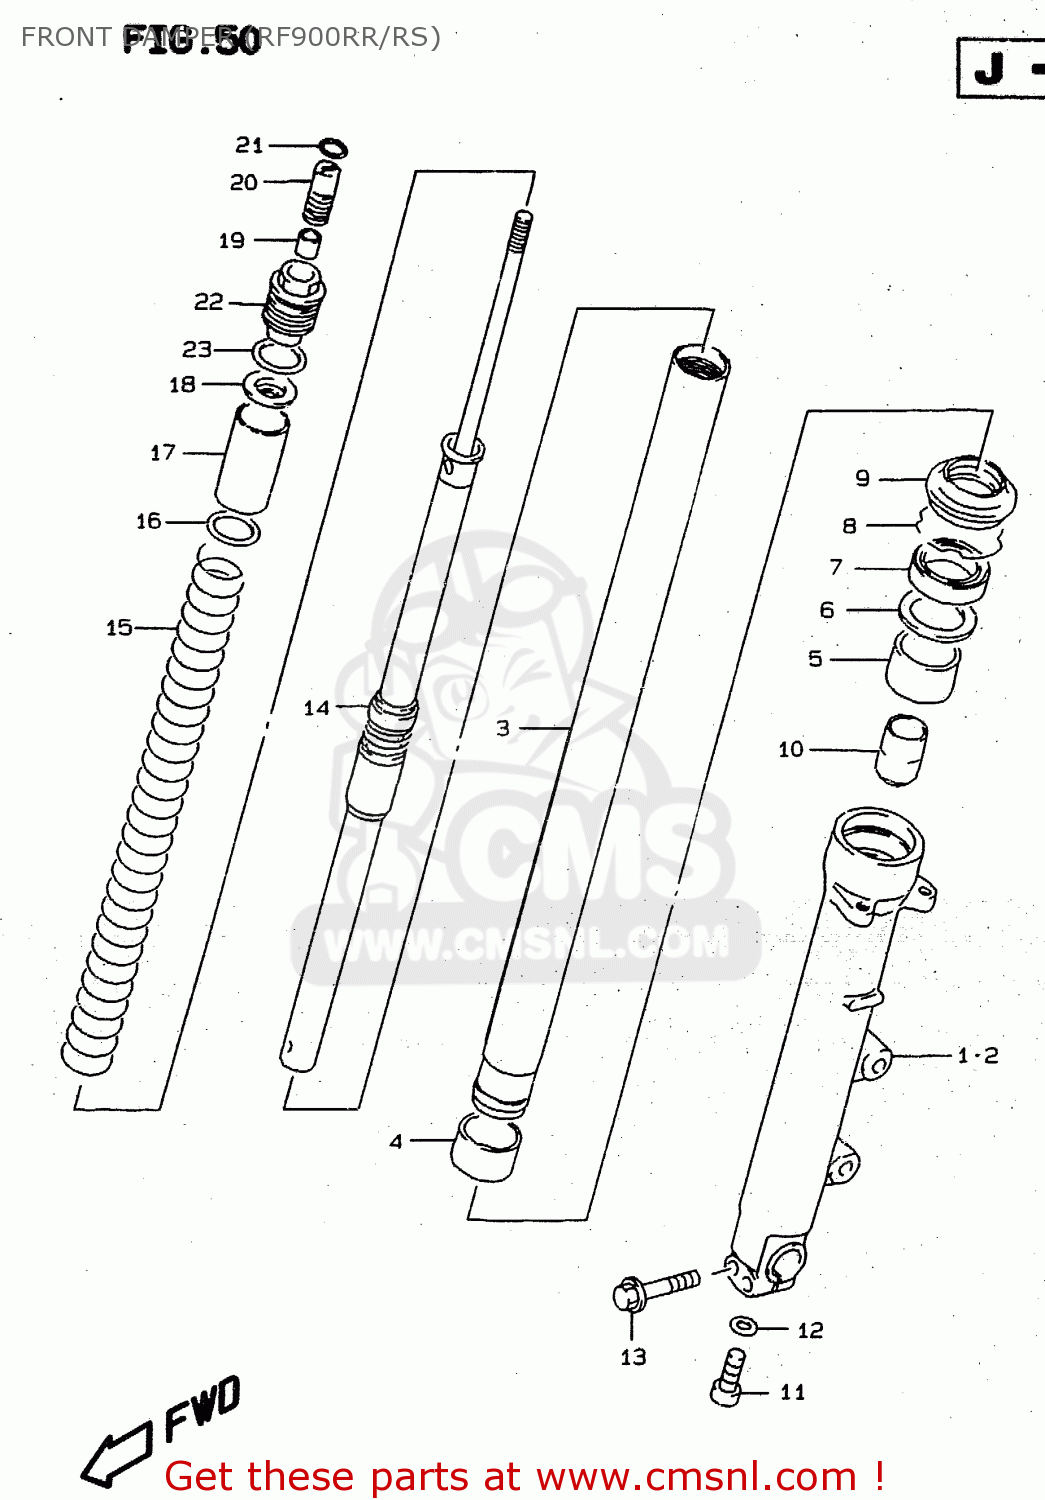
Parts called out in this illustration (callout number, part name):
1	TUBE,OUTER,R
2	TUBE,OUTER,L
3	TUBE,INNER
4	BUSH,SLIDE
5	BUSH,GUIDE
6	SPACER,SEAL
7	SEAL,OIL
8	CIRCLIP,FORK OIL SEAL
9	SEAL,DUST
10	PIECE,OIL LOCK
11	BOLT(8X27)
12	GASKET (NAS)
13	BOLT
14	DAMPER,FR
15	SPRING,MAIN
16	SEAT,SPRING LWR
17	COLLAR,SPRING(35X37X50)
18	SEAT,SPRING UPR
19	NUT
20	ADJUSTER,SPRING
21	O RING
22	BOLT,FORK
23	O RING
